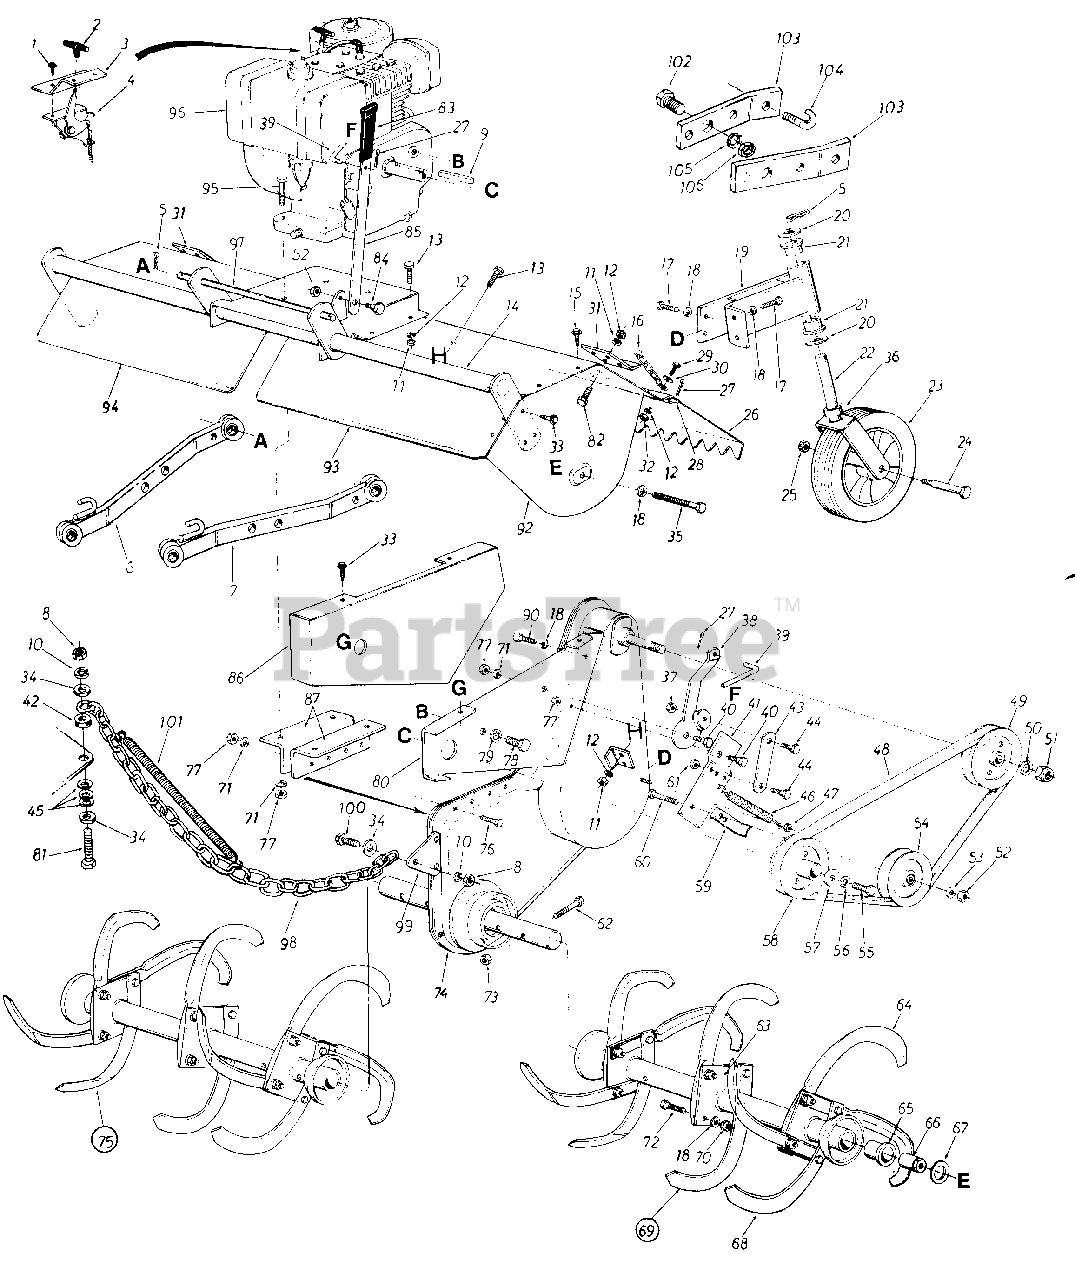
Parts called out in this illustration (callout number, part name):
1	Hex Wash. Hd. Self-Tap Scr. #8 x .50" Lg.
2	Throttle Control Knob-
3	Throttle Control Bracket
4	Throttle Control Ass'y. Comp.
5	Internal Cotter Pin
6	Draft Bar Ass'y.-R.H.
7	Draft Bar Ass'y.-L.H.
8	Hex Nut 3/8-24 Thd.*
9	Sq. Key 1/4" x 1/4" x 2.00" Lg.
10	L-Wash. 3/8" I.D.*
11	Hex Nut 1/4-28 Thd.
12	L-Wash. 1/4" I.D.*
13	Hex Bolt 1/4-28 x .62" Lg.*
16	#2 Dog Chain x 20" Lg.
17	Hex Wash. Hd. Self-Tap Scr. 318-24 x .75" Lg.
18	L-Wash. 3/8" I.D.*
21	Flange Bearing 3/4" I.D. x 1.00 O.D.
24	Shoulder Bolt .623" I.D. x 3.62" Lg.
25	Hex Cent. L-Nut 7/16-14 Thd.
28	L.H. Flap Rod
29	Hex Bolt 1/4-20 x .62" Lg.*
30	Fl-Wash. 1/4" I.D.
33	Hex Wash. Hd. Self-Tap Scr. 1/4" x .62" Lg.
34	Fl-Wash. .385" I.D. x 1.0" O.D. x .135 Thk.
35	Hex Bolt 3/8-16 x 1.25" Lg.*
36	Spacer .752" I.D. x 1.25" O.D.
37	Hex Cent. L-Nut 5/16-18 Thd.
40	Shoulder Bolt 7/16" Dia. x 1.75" Lg.
45	Fl-Wash. .406" I.D. x .74" O.D. x .063 Thk.
46	Extension Spring .62" O.D. x 6.12" Lg.
47	Hex Crown Nut 3/8-24 Thd.
48	"V"-Belt 1/2" x 43" Lg. [ (Kevlar)
49	1/2" "V"-Pulley 4.75" O.D. x .625" Bore
50	L-Wash. 5/8" I.D.*
51	Hex Ins. L-Nut 5/8-18 Thd.
52	Hex Cent. L-Nut 3/8-16 Thd.
53	Fl-Wash. 3/8" I.D.
54	Idler Pulley 4.0" O.D.
55	Hex Bolt
56	L-Wash. 7/16" I.D.*
57	Fl-Wash. 7/16" I.D. x 1.38" O.D.
58	1/2" "V"-Pulley .475" O.D. x 1.00" Bore
61	Hex Cent. L-Nut 5/16-18 Thd.
62	Hex Bolt 7/16-14 x 2.00" Lg.
66	Spacer
67	Thrust Wash. 1/2" I.D. x 1.55" O.D.
71	L-Wash. 5/16" I.D.*
72	Hex Bolt 3/8-24 x 1.5" Lg.*
73	Hex Cent. L-Nut 7/16-14 Thd.
77	Hex Nut 5/16-18 Thd.*
78	Hex Bolt 1/2-20 x .88" Lg. (Grade 5)
79	L-Wash. 1/2" I.D.*
80	Clutch Support Bracket
81	Hex Bolt 3/8-24 x 1.75" Lg.*
82	Hex Bolt 1/4-28 x .75" Lg.
83	Plastic Grip
84	Shoulder Bolt .498 Dia. x .212 Lg.
85	Clutch Handle
96	8 H.P. Engine
97	Tiller Mounting Shaft 16" Lg.
98	Chain 23" Lg.
99	Tiller Mounting Bracket
100	Hex Bolt 3/8-24 x 1.25" Lg.*
101	Extension Spring
102	Hex Bolt 5/8-18 x 1.62" Special
103	Drag Link Extension
104	Hitch Chain Hook
105	L-Wash. 518" I.D.*
106	Hex Jam Nut 5/8-18 Thd.
